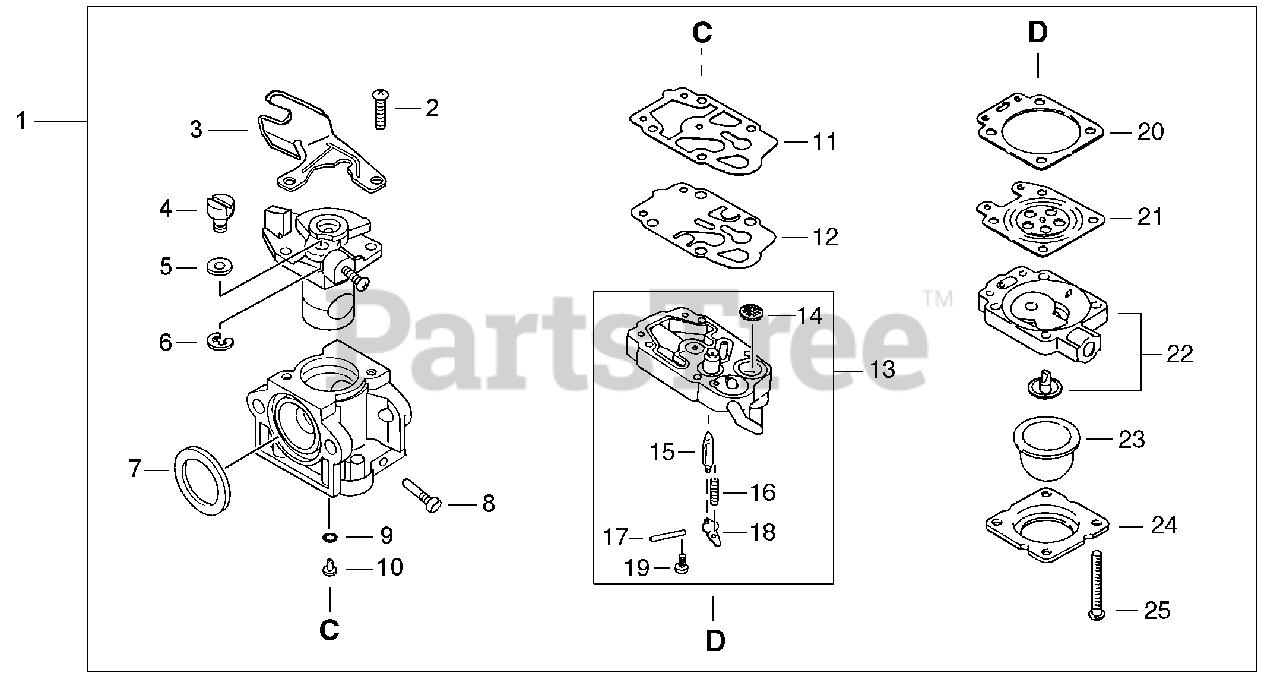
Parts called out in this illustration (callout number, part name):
1	CARBURETOR WYK-201
3	BRACKET, CABLE
6	RING, RETAINING
8	NEEDLE - HIGH SPEED
9	O-RING
10	JET, MAIN
11	GASKET, PUMP
12	DIAPHRAGM, PUMP
13	BASE, PURGE
14	STRAINER
15	VALVE, INLET NEEDLE
16	SPRING, METERING LEVER
17	PIN, METERING LEVER
18	LEVER, METERING
19	SCREW, METERING LEVER PIN
20	GASKET, METERING
21	DIAPHRAGM, METERING
22	PURGE BASE ASSY
23	BULB, PURGE
24	RETAINER, PURGE BULB
25	SCREW, PUMP COVER
